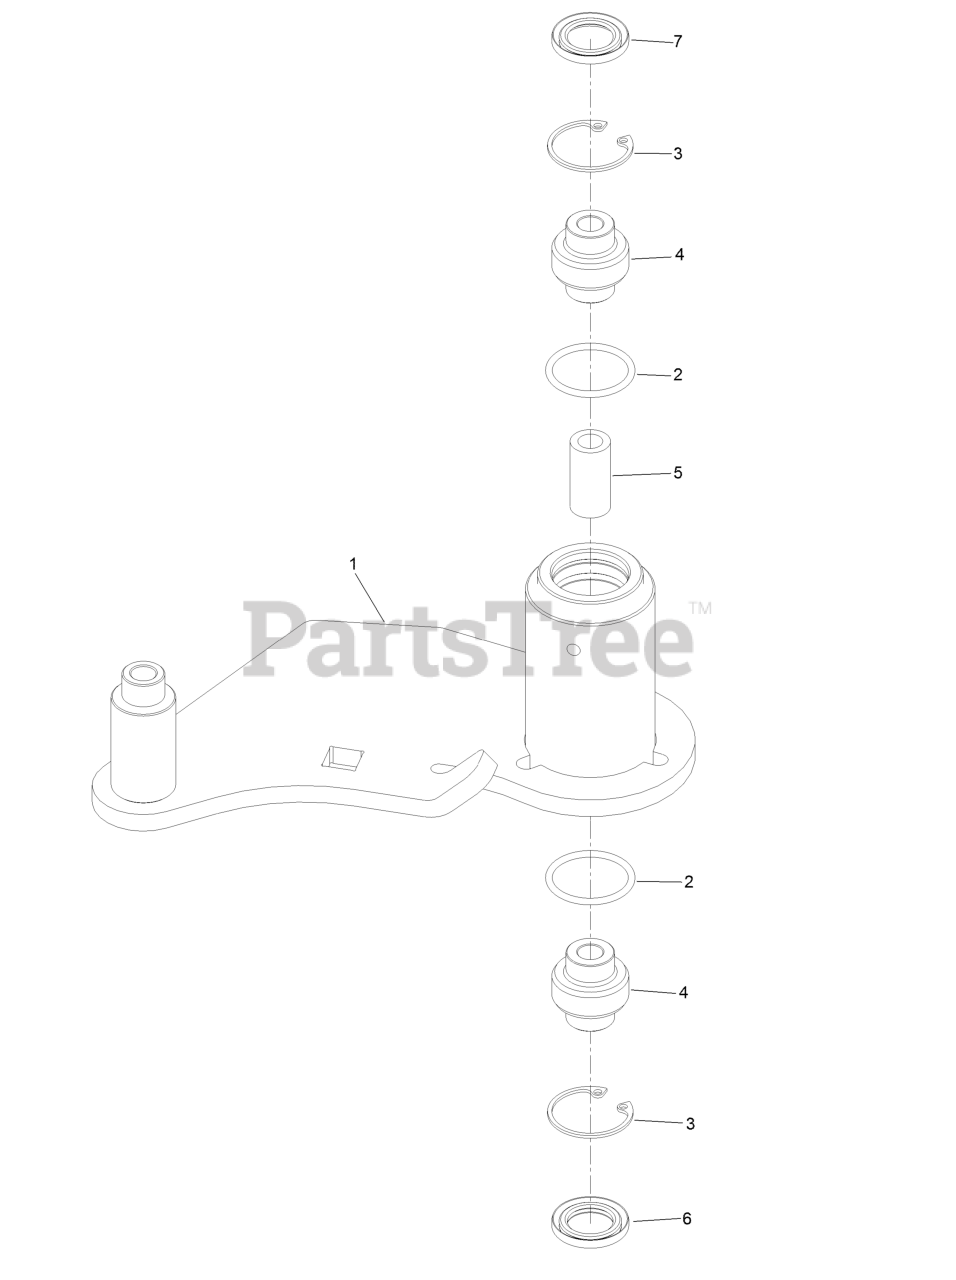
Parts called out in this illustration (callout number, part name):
1	Idler-Deck
3	Ring-Snap
4	Bearing-Spherical
6	Seal-Lip, Double
7	Seal-Lip, Single
